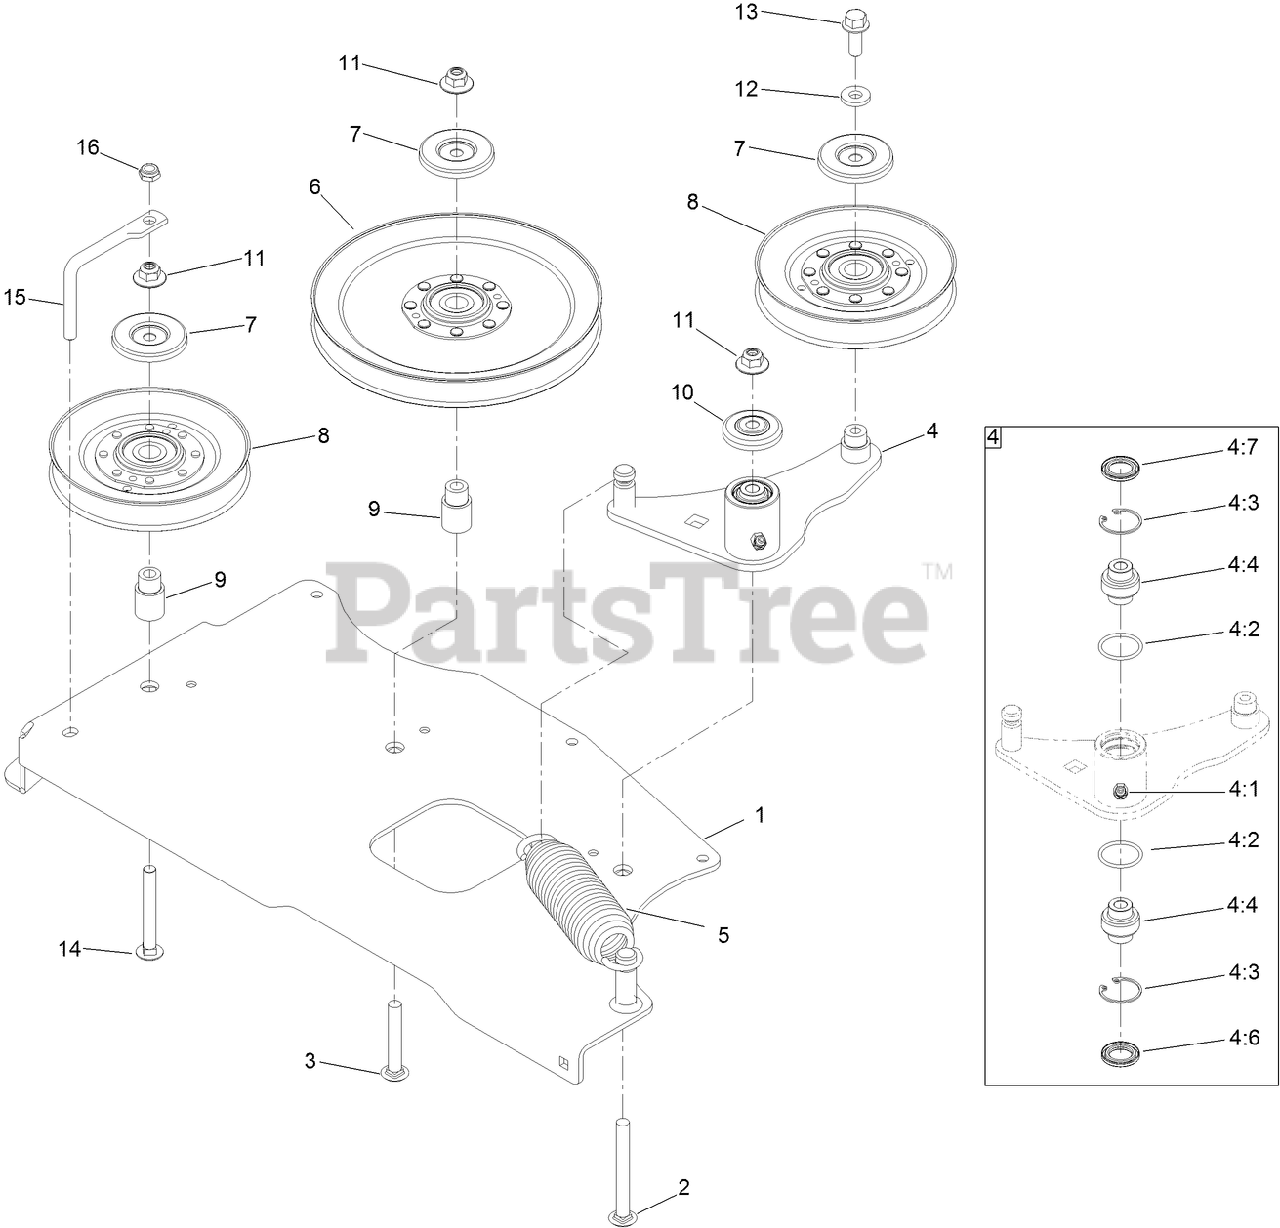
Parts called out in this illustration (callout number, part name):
1	MOUNT-IDLER
2	BOLT-SHOULDER, CARRIAGE
3	SCREW-CARR
4	IDLER ARM ASM
4:1	FITTING-LUBE, 45 DEG
4:2	O-RING
4:3	RING-SNAP
4:4	BEARING-SPHERICAL
4:6	SEAL-LIP, DOUBLE
4:7	SEAL-LIP, SINGLE
5	SPRING-EXTENSION
6	IDLER-V
7	SHIELD-DUST
8	IDLER V
9	STANDOFF-IDLER
10	GUARD-TOP
11	NUT-FLANGE, NI
12	SPACER
13	SCREW-HHF
14	SCREW-CARR
15	GUIDE-BELT
